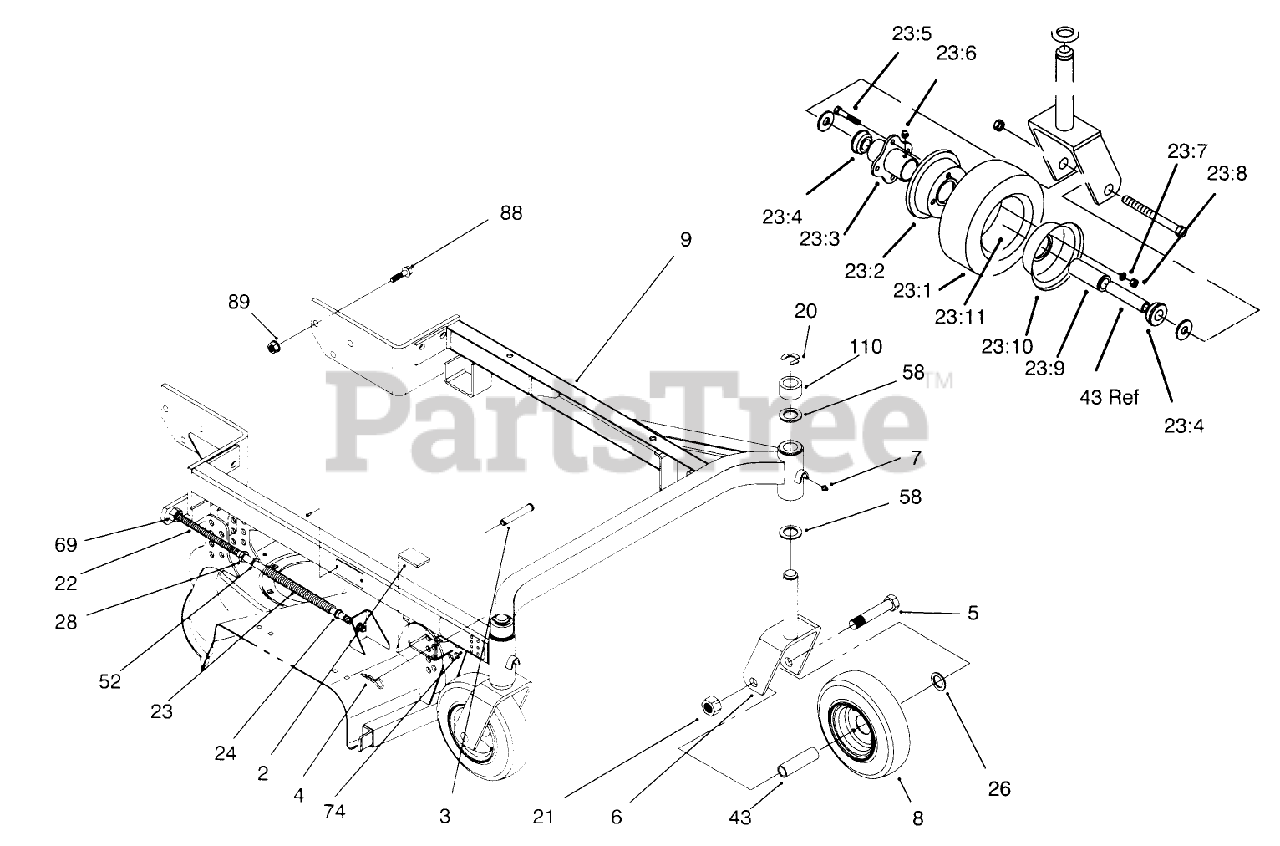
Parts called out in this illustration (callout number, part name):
2	CUSHION-RUBBER
3	PIN-CLEVIS
4	PIN-HAIR
5	SCREW-HH
6	Fork
7	FITTING-GREASE
8:1	PNEUMATIC WHEEL ASM
8:2	BEARING-OUTSIDE
8:2	FEMALE WHEEL HALF
8:3	BEARING-ROLLER
8:3	HUB-CENTER
8:4	BEARING-OUTSIDE
8:5	WHEEL BOLT
8:6	FITTING-GREASE
8:7	WASHER-LOCK
8:8	NUT-HEX
8:9	SPANNER-TIRE
8:10	MALE WHEEL HALF
8:11	TUBE-INNER (W/VALVE)
9	WA - CARRIER FRAME 52"
20	RING-RETAINING
21	NUT-HEX
22	SHAFT-ADJUSTING
23	SPRING
24	BUSHING-FLANGE
26	WASHER-FLAT
28	NUT-JAM
43	SPANNER-TIRE
52	WASHER
58	WASHER-THRUST
59	RIVET-POP
60	Plate-Serial
69	NUT-LOCK, NI
74	DECAL-HOC, RH
77	DECAL-HOC, LH
88	SCREW-HHF
89	NUT-HF
110	SPACER-CASTOR
